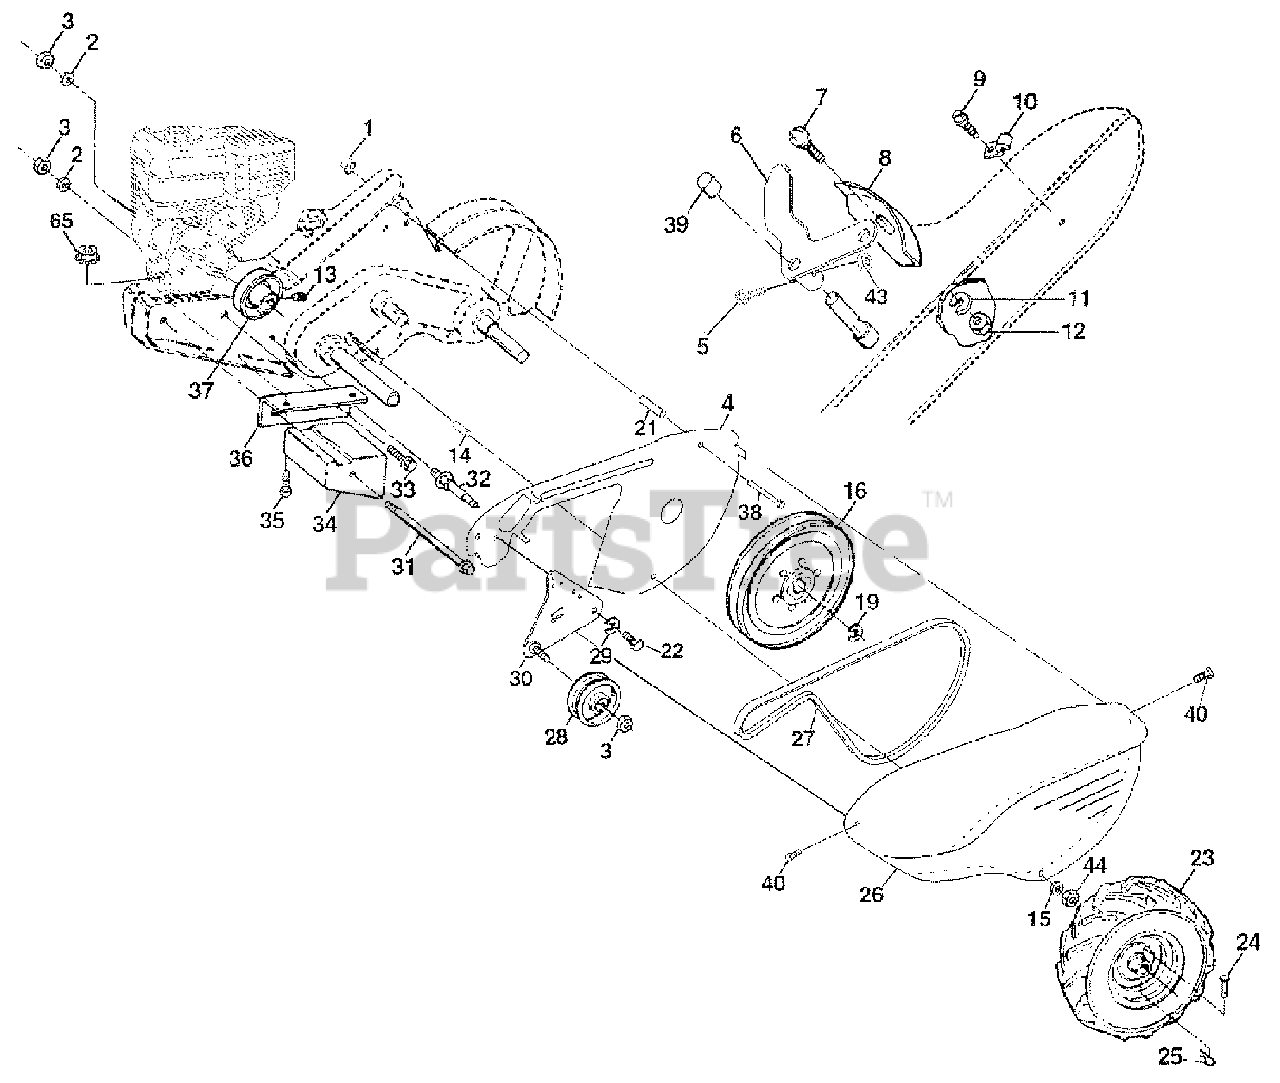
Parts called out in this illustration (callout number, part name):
1	Nut, Keps 5/16-18
2	Washer, Lock 3/8
3	Nut, Hex 3/8-16
4	Shield, Inner Belt Guard
5	Screw, Shift Lever
6	Lever, Shift
7	Bolt, Carriage 1/4-20 x 1/2 Gr. 5
8	Plate, Shift Indicator
9	Screw, Hex, Washer Head, Slotted #10-24x1/2
10	Clip
11	Washer, Lock 1/4
12	Nut, Hex 1/4-20
13	Screw, Set, Hex 5/16-18 x 3/8
14	Spacer, Split 0.327x0.42x1.220
15	Washer 11/32 x 11/16x 16Ga.
16	Sheave, Transmission
19	Ring, Retainer
21	Spacer, Split 0.327x0.42x2.09
22	Bolt, Fin Hx 5/16-24x1/2
23	Tire
23	Tire Valve
24	Rivet, Drilled
25	Clip, Hairpin
26	Guard, Belt
27	Belt, V
28	Pulley, Idler
29	Ring, Klip
30	Bracket, Idler
31	Bolt, Hex 5/16-16x12
32	Shaft, Idler Arm
33	Bolt, Hex 3/8-16x1
34	Counterweight, L.H.
35	Bolt, Hex 5/16-18 x 1-1/2
36	Bracket, Reinforcement, L. H.
37	Sheave, Engine
38	Bolt, Fin Hx 5/16-18 x 2-3/4
39	Cap, Plunger
40	Screw Hx Wsh Slt #10-24 x 1/2
43	Nut, Lock #10-24
44	Nut, Lock 5/16-18 PI
65	Nut, Lock Hex Flg
